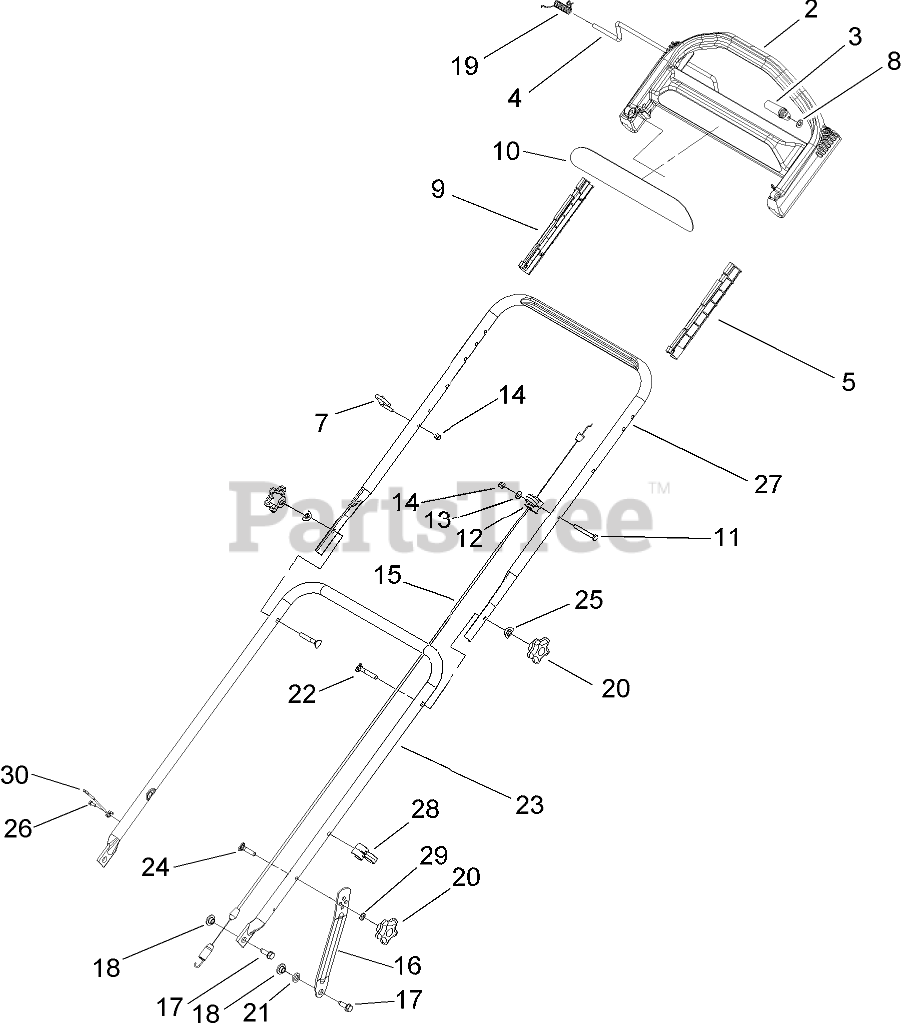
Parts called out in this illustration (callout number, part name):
2	HANDLE-CONTROL
3	LEVER-TRACTION
4	BAR-CONTROL, TRACTION
5	GUIDE-LH
7	GUIDE-ROPE
8	WASHER-PLAIN
9	GUIDE-RH
10	DECAL-HANDLE
11	SCREW-HH
12	ANCHOR-CABLE, UPPER
13	WASHER-FLAT
14	NUT-LOCK, NI
15	CABLE-TRACTION
16	SUPPORT-HANDLE
17	SCREW-HWHTF
18	SPACER-COUPLING
19	Spring-Torsion
20	KNOB-HANDLE
21	WASHER
22	SCREW-HANDLE
23	HANDLE-LOWER
24	SCREW-HANDLE
25	WASHER
26	SCREW-SHWH, THREAD FORMING
27	HANDLE-UPPER
28	Guide-Cable
29	WASHER-LOCK
30	HOOK-ROPE, DISPLACEMENT
